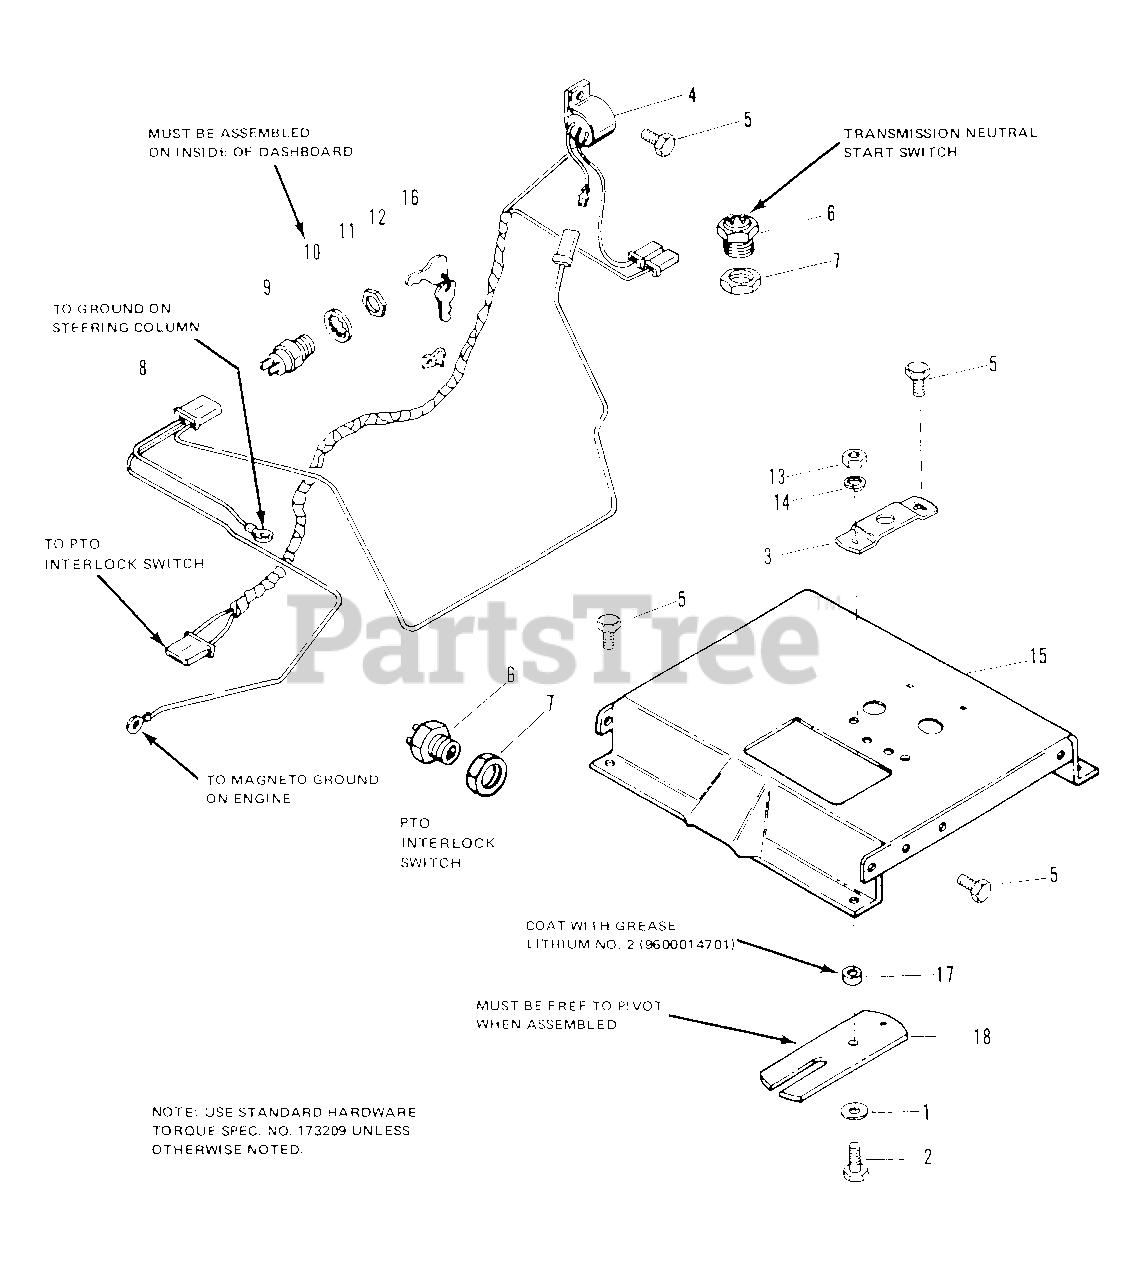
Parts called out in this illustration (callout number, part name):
2	CAPSCREW, Hex, 5/16-18 x 1
3	BRACKET, Switch
4	IGNITION, Interlock
5	SCREW, Taptite, Washer Hd., 1/4-20 x 3/8
6	SWITCH, Interlock
7	NUT, Lock, 9/16-18
8	WIRING HARNESS
9	SWITCH, Manual Start
10	LOCKWASHER, Internal Tooth, 5/8
11	NUT, Hex, 5/8-32 (Ignition)
12	CLIP, Speed
13	NUT, Hex, 5/16-18
14	LOCKWASHER, Spring, 5/16
15	SUPPORT, Frame
16	KEYS & RING ASSY
18	LEVER, Switch
